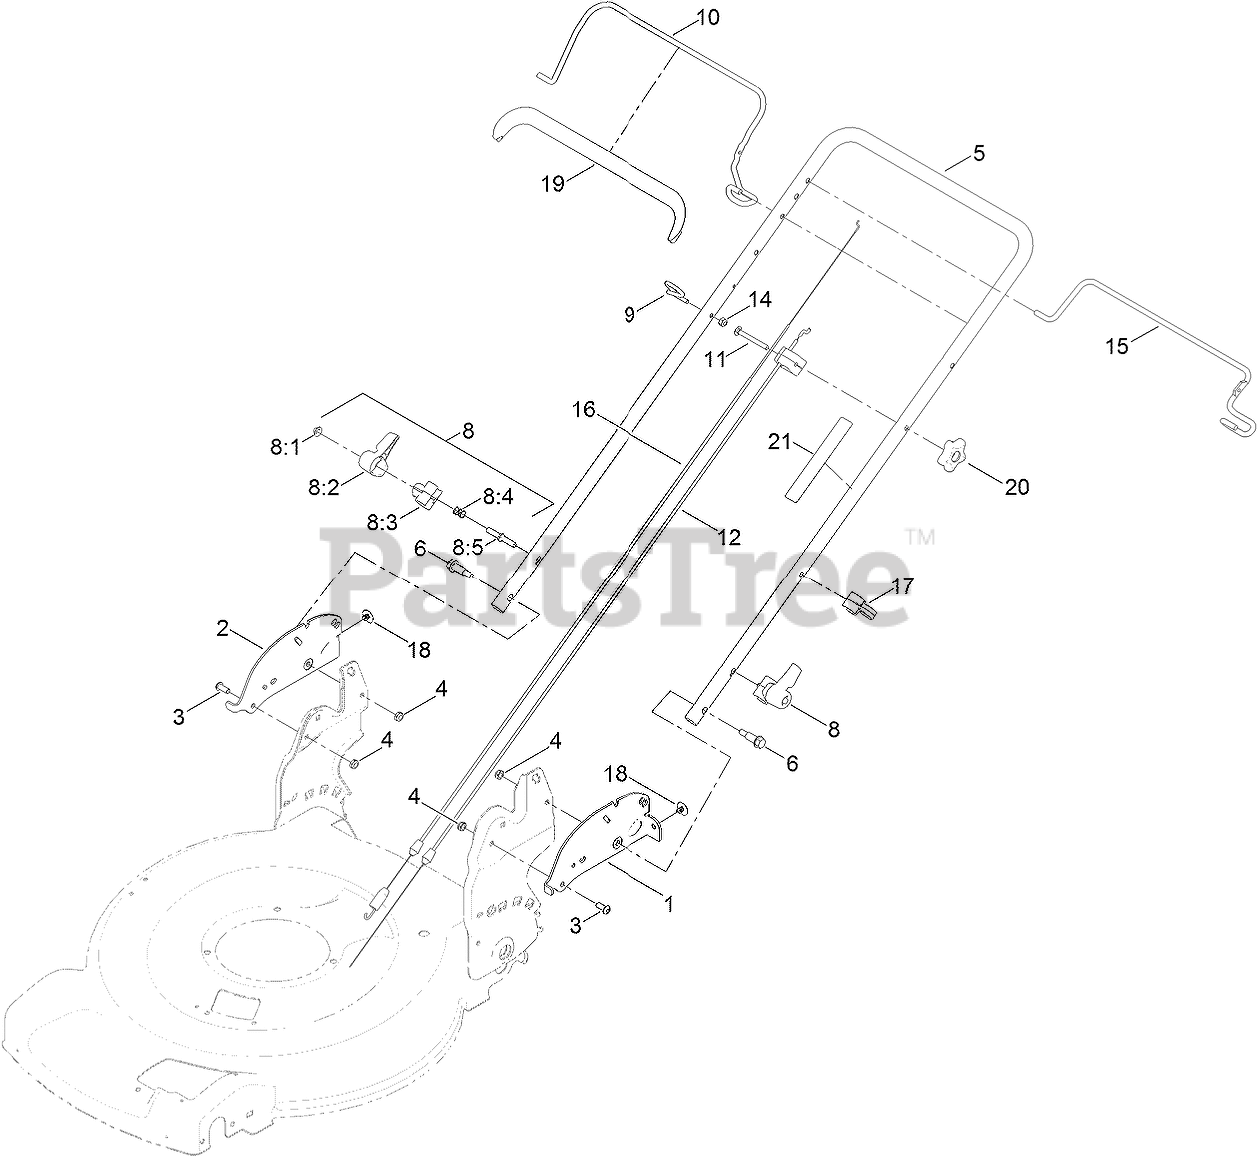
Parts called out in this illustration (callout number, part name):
1	PLATE-HANDLE, LH RWD
2	PLATE-HANDLE, RH RWD
3	SCREW-HSBH
4	NUT-LOCK, NI
6	BOLT-SHOULDER
8	QUICK RELEASE ASM
8:1	NUT-PUSH
8:2	LEVER
8:3	ANCHOR-SPRING
8:4	SPRING-COMPRESSION
8:5	ROD-RELEASE
9	GUIDE-ROPE
10	BAIL-BRAKE
11	SCREW-CARR
12	CABLE-BRAKE
14	NUT-LOCK, NI
15	BAIL-TRACTION
16	CABLE-TRACTION
17	GUIDE-CABLE
18	CLIP-TREE
19	COVER-BAIL
20	KNOB-HANDLE, LOCKING
21	DECAL-TRACTION, ADJUST
